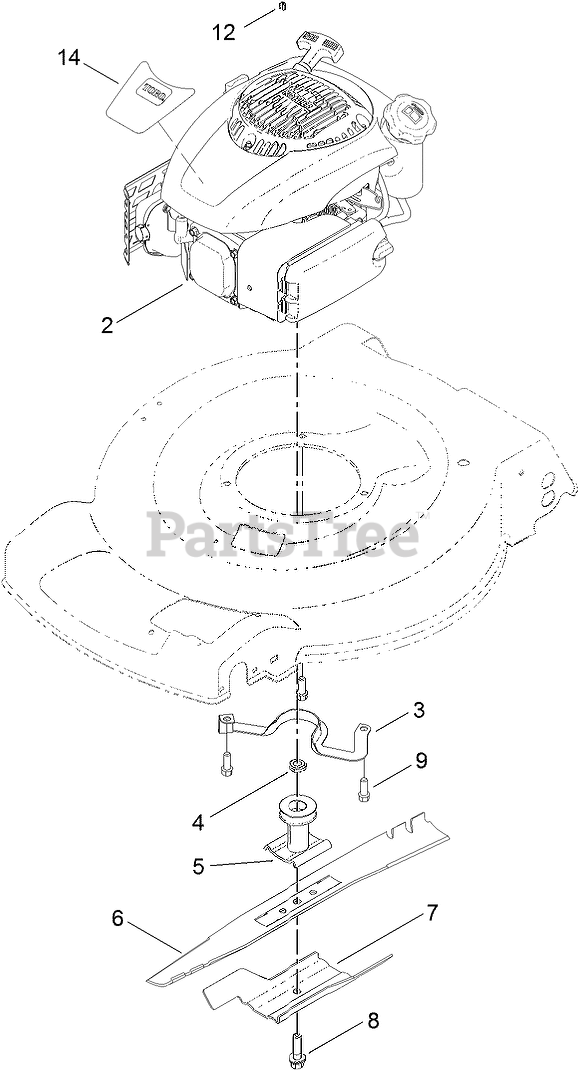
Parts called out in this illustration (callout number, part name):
3	Guide-Belt
4	Spacer-Driver
5	DRIVER-BLADE
6	BLADE-22 INCH
7	SUPPORT-BLADE
8	BOLT-BLADE
9	SCREW-TAPTITE
12	STOP-ROPE
14	DECAL-SHROUD
